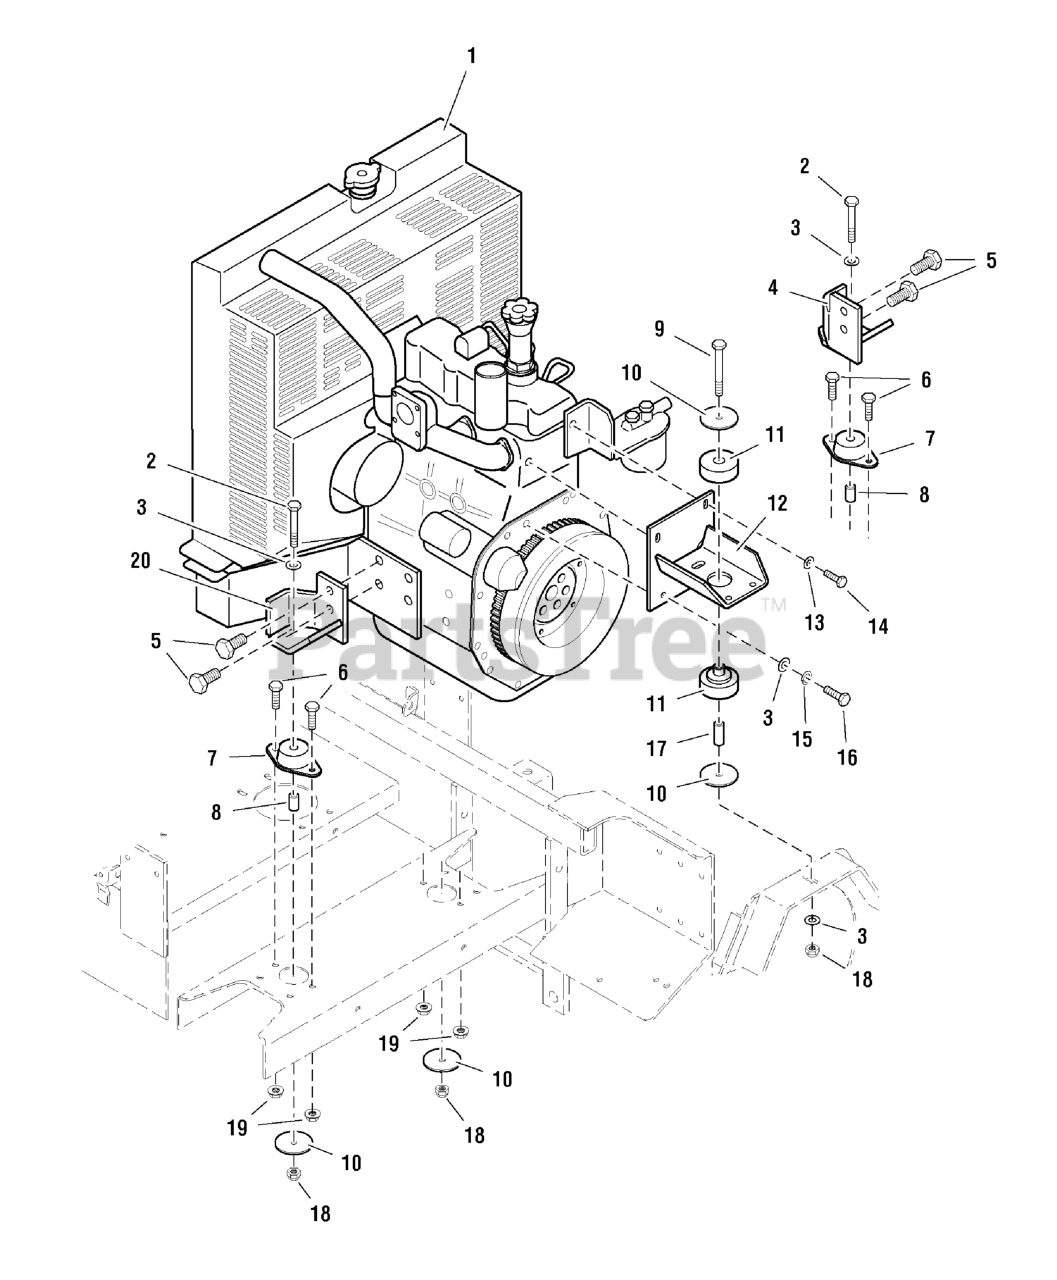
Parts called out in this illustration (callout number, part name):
1	ENGINE, Caterpillar
2	BOLT, 3/8-16 X 2-1/2" GD5 CZ
3	WASHER, 3/8 SAE
4	MOTOR MOUNT - RH
5	BOLT, M14 x 30MM
6	BOLT, 3/8-16 X 1" GD5 CZ
7	ISO MOUNT, Front
8	SPACER, .38 x .50 x 1.00
9	BOLT, 3/8-16 X 3" GD5 CZ
10	WASHER, 3/8 x 2-1/2
11	ISO MOUNT, Rear (2 piece)
12	MOTOR MOUNT - Upper
13	WASHER, 5/16" SAE
14	BOLT, M8 x 20MM
15	WASHER, 3/8" Lock
16	BOLT, M10 x 30MM
17	SPACER, .38 x .62 x 1.62
18	NUT, 3/8-16 HEX NYLON LOCK
19	NUT, 3/8-16 Hex Serrated Flange
20	MOTOR MOUNT - LH
